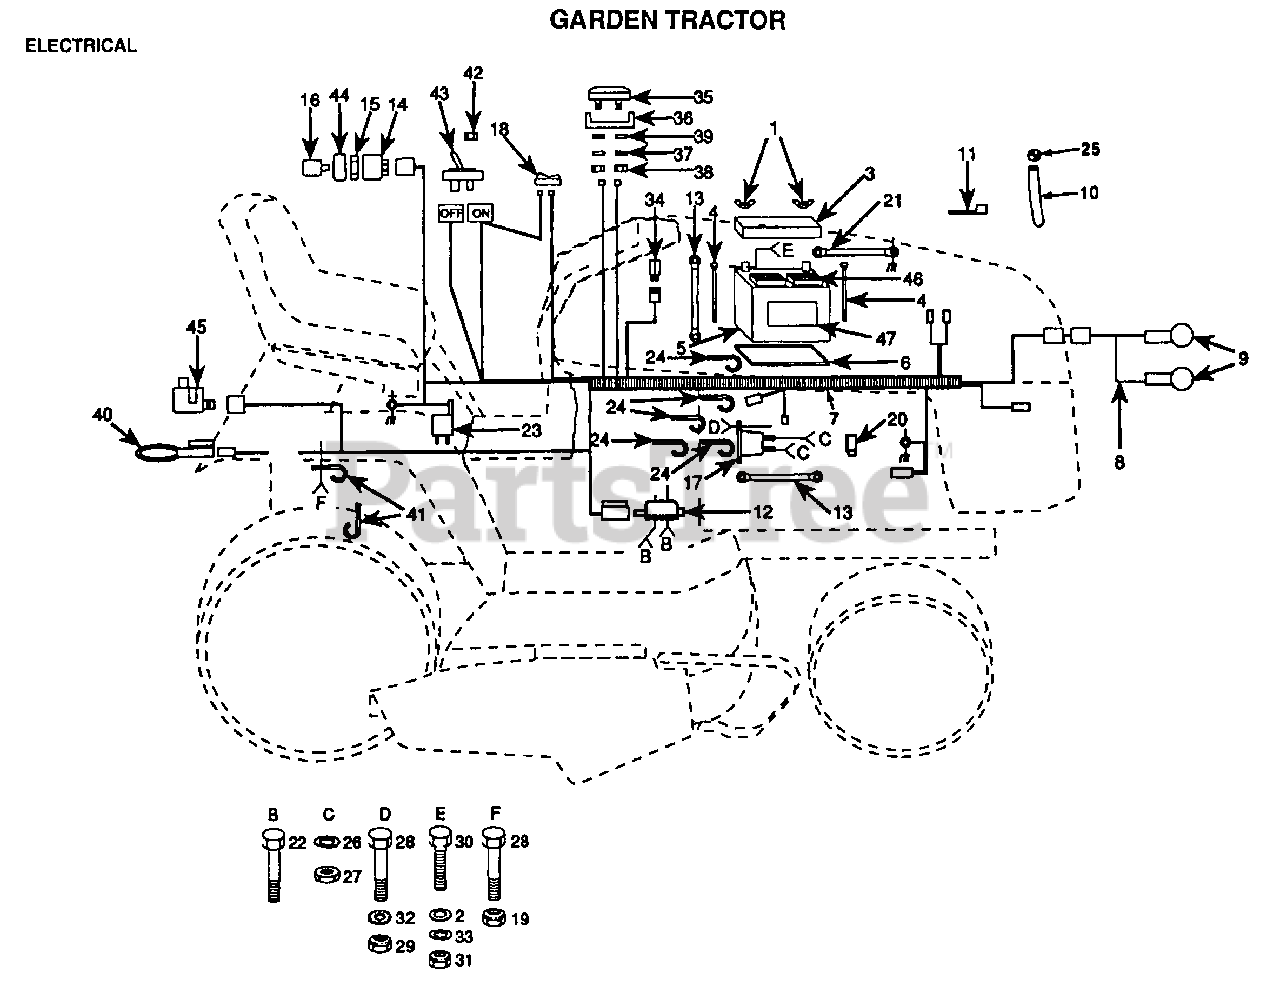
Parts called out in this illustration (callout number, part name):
2	WASHER
4	BOLT
6	"TRAY T, BATTERY"
7	HARNESS
11	WIRE TIE
12	SWITCH-INTER. GT
13	CABLE-BATTERY T
16	KEY
18	SWITCH LT
21	CABLE T
22	SCREW
23	RELAY ASSY T
24	CLIP T
25	HOSE CLAMP T
27	NUT
28	BOLT
29	NUT
30	BOLT LT
33	LOCKWASHER
34	FUSE HYT
35	AMMETER T
39	WASHER
41	CLIPT
42	HEX NUT T
45	SWITCH SEAT
46	"CAP,BATTERY "
47	DECAL
